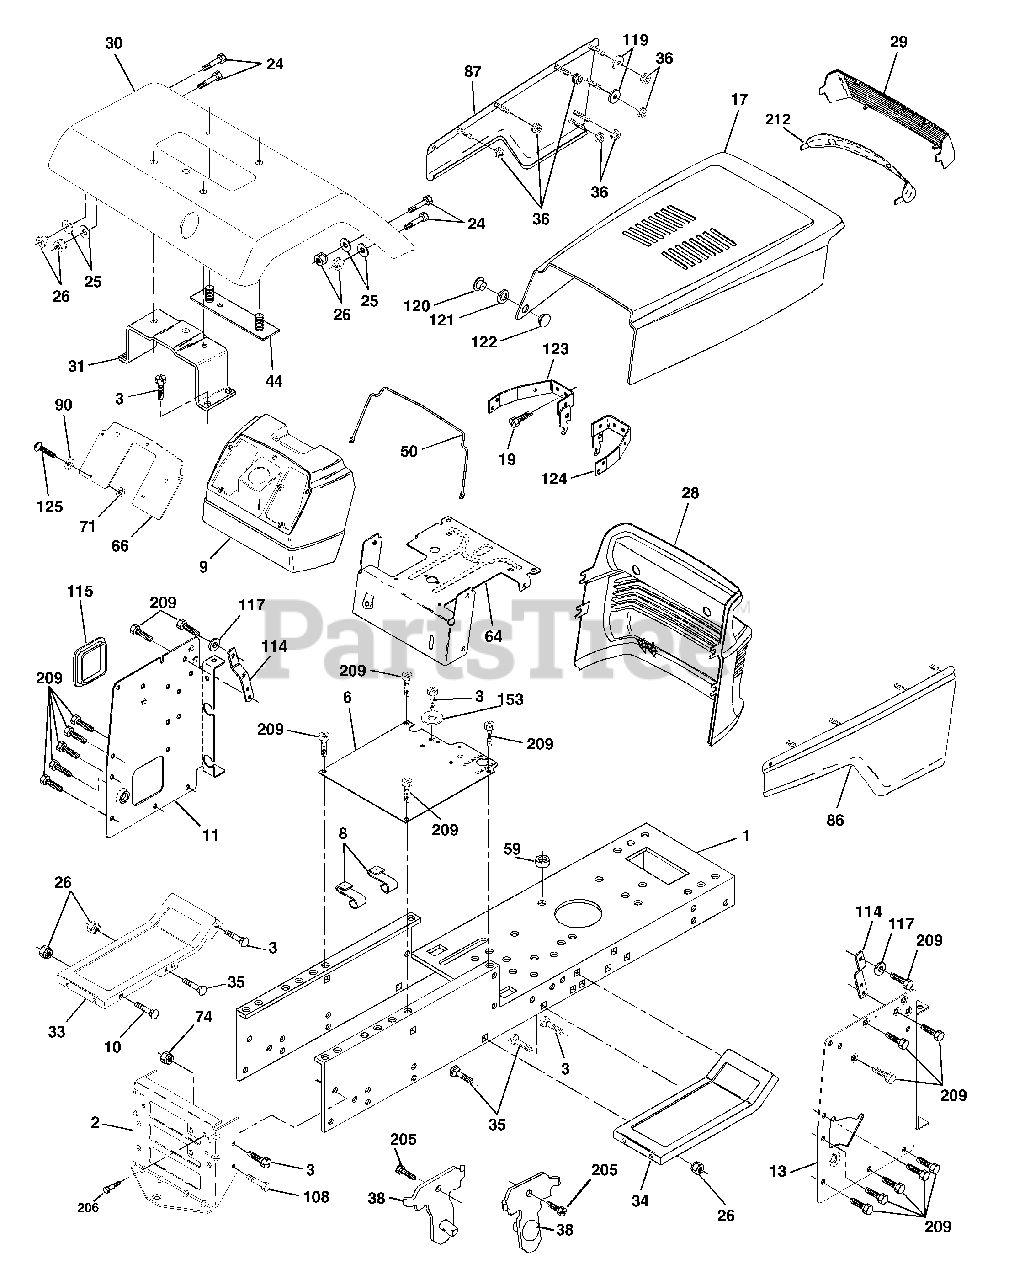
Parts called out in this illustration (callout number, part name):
1	Chassis
2	Drawbar
3	Screw 3/8-16 x 3/4
6	Saddle Flat Lt
8	Clip Insulator
10	Bolt Rd Hd Sqnk. 3/8-16 Unc x 1
11	Panel Dash Lh
13	Panel Dash Rh
19	Screw Hwhd Hi-Lo #13-16 x 3/4
24	Bolt Fin Hex 3/8-16 Unc x 1 Gr. 5
25	Washer 13/32 x 13/16 x 12 Ga.
26	Nut Lock Hex w/Insert 3/8-16 UNC
28	Grill / Lens Asm
29	Lens Grille
30	Fender Asm YTGT
31	Bracket Fender
33	Footrest Pnt. Lh
34	Footrest Pnt. Rh
35	Bolt Rd Hd Sht. Sqnk. 3/8-16 x 3/4
36	Nut Pal
38	Bracket Asm Pivot Mower Rear
44	Strap Asm Fender
50	Rod Support Hood
59	Bushing Snap Split
64	Dash Lower
66	Plate Dash Slkscr.
71	Nut Keps Hex 1/4-20 Unc
74	Nut Crownlock 3/8-16 Unc
86	Panel Asm. Pnt. Side Rh
87	Panel Asm. Pnt. Side Lh
90	Washer 9/32 x 3/4 x 16 Ga.
108	Bolt Fin Hex 3/8-16 Unc x 3/4
114	Bracket Support Dash
115	Cover Access
117	Washer Serrated Disc 13/32 x 1
119	Washer 9/32 x 1-1/4 x 16 Ga.
120	Rivet Ratchet Female
121	Washer Nylon
122	Rivet Ratchet Male
123	Bracket Asm. Pivot Hood Lh
124	Bracket Asm. Pivot Hood Rh
125	Screw Mach Cr. 1/4-20 x 3/4
153	Washer 13/32 x 1-3/8 x 3 Ga.
205	Screw Thdrol 3/8-16 x 1/2
206	Bolt Shoulder 5/16-18
209	Screw Hex wsh Thdrol 3/8-16 x 3/4
212	Insert Lens Reflector
